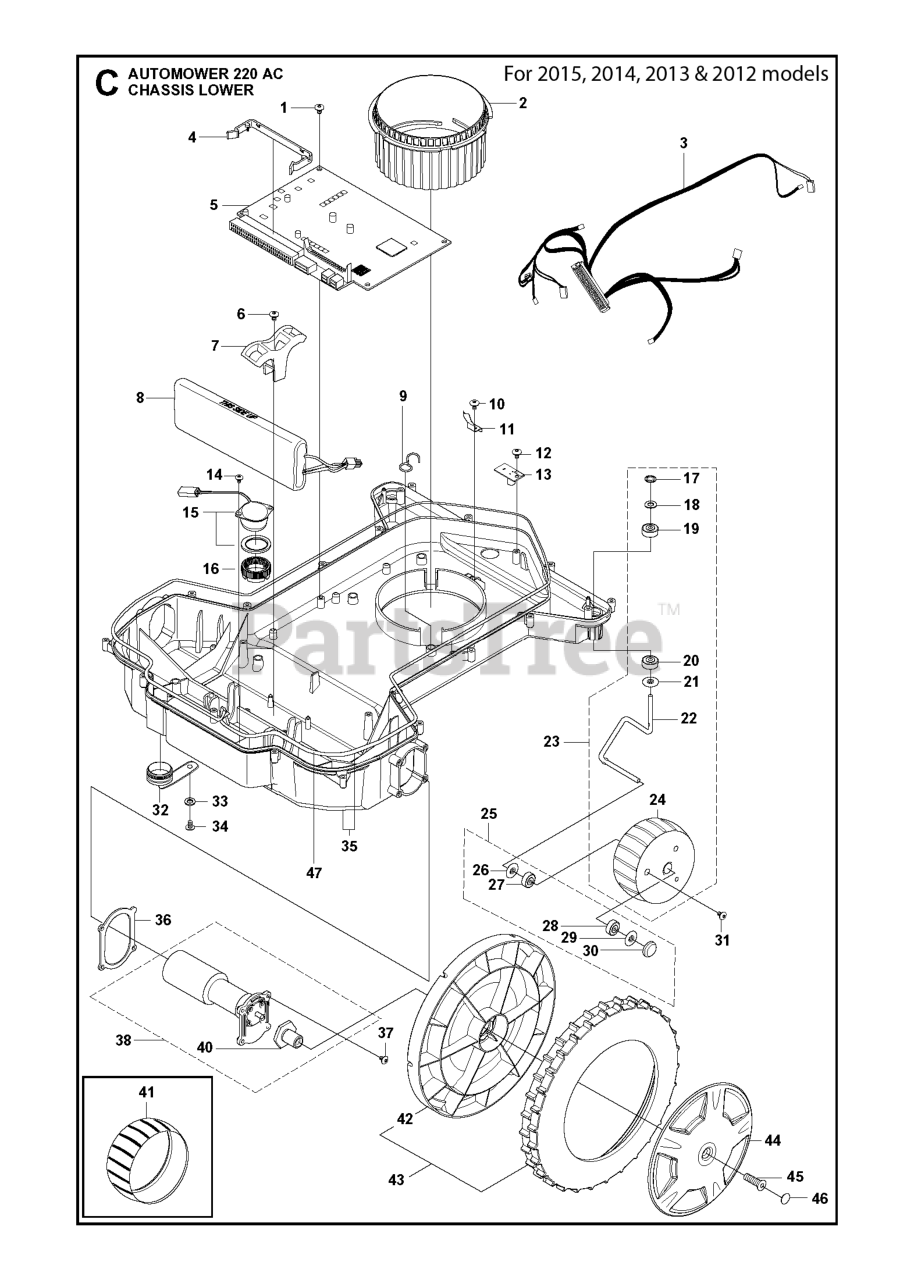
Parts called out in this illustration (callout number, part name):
1	SCREW SILVER 10MM
2	CUTTING HEIGHT NUT
3	MAIN WIRING
4	CLIP MAIN CONNECTOR 50PCS
4	CLIP MAIN CONNECTOR
5	PRINTED CIRCUIT ASSY PCBA AM22
6	SCREW 14MM
11	LOCKING SPRING
12	SCREW SILVER 10MM
16	NUT BUZZER
17	LOCKWASHER STARLOCK SS 6MM GEO
18	WASHER 6.4X12X1.6 SS
19	BALL BEARING
20	BALL BEARING
23	KIT 6MM AXLE KIT - STANDARD WH
24	WHEEL, FRONT
25	BEARING KIT 6MM AXLE
27	BALL BEARING
28	BALL BEARING
30	COVER WASHER
31	SCREW ITXPANT PT 40 THREAD
32	PLUG SERVICE PLUG
34	SCREW 14MM
35	CHASSIS LOWER
38	MOTOR ASSY
41	WHEEL RUBBER TYRE
43	GEAR WHEEL
46	COVER WASHER
47	SEALING STRIP G2-2 CHASSIS
